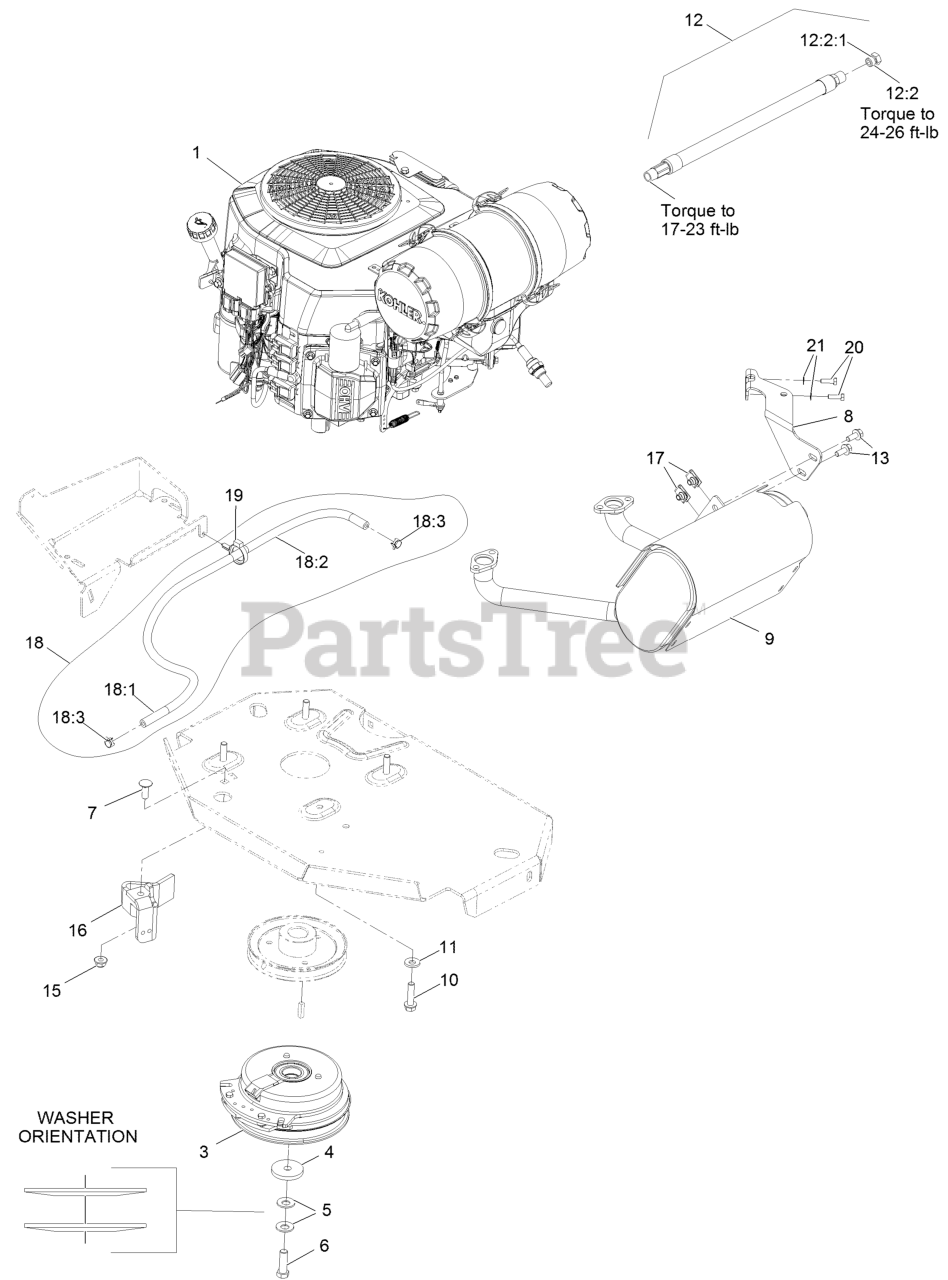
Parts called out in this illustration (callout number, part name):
1	Engine - Kohler Ecv740-3039 W/E-Gov
3	CLUTCH KIT
4	WASHER-CLUTCH
5	WASHER-SPRING
6	SCREW-HH 7/16-20 X 1 1/2 W/LOCTITE
7	SCREW-CARR
8	MUFFLER BRACKET KIT
10	SCREW-HWH
11	WASHER-BELLEVILLE
12	OIL DRAIN HOSE ASM
12:2	PLUG-HH
12:2:1	O-RING
13	SCREW-HHF
15	NUT-HF, NI
16	CLUTCH-ANCHOR
18	FUEL LINE ASM
18:1	HOSE-FUEL
18:2	SLEEVE-THERMAL
18:3	CLAMP-HOSE
19	CLAMP-HOSE
20	SCREW-HH M6-1 X 20Mm W/Patch
21	WASHER-SPRING
